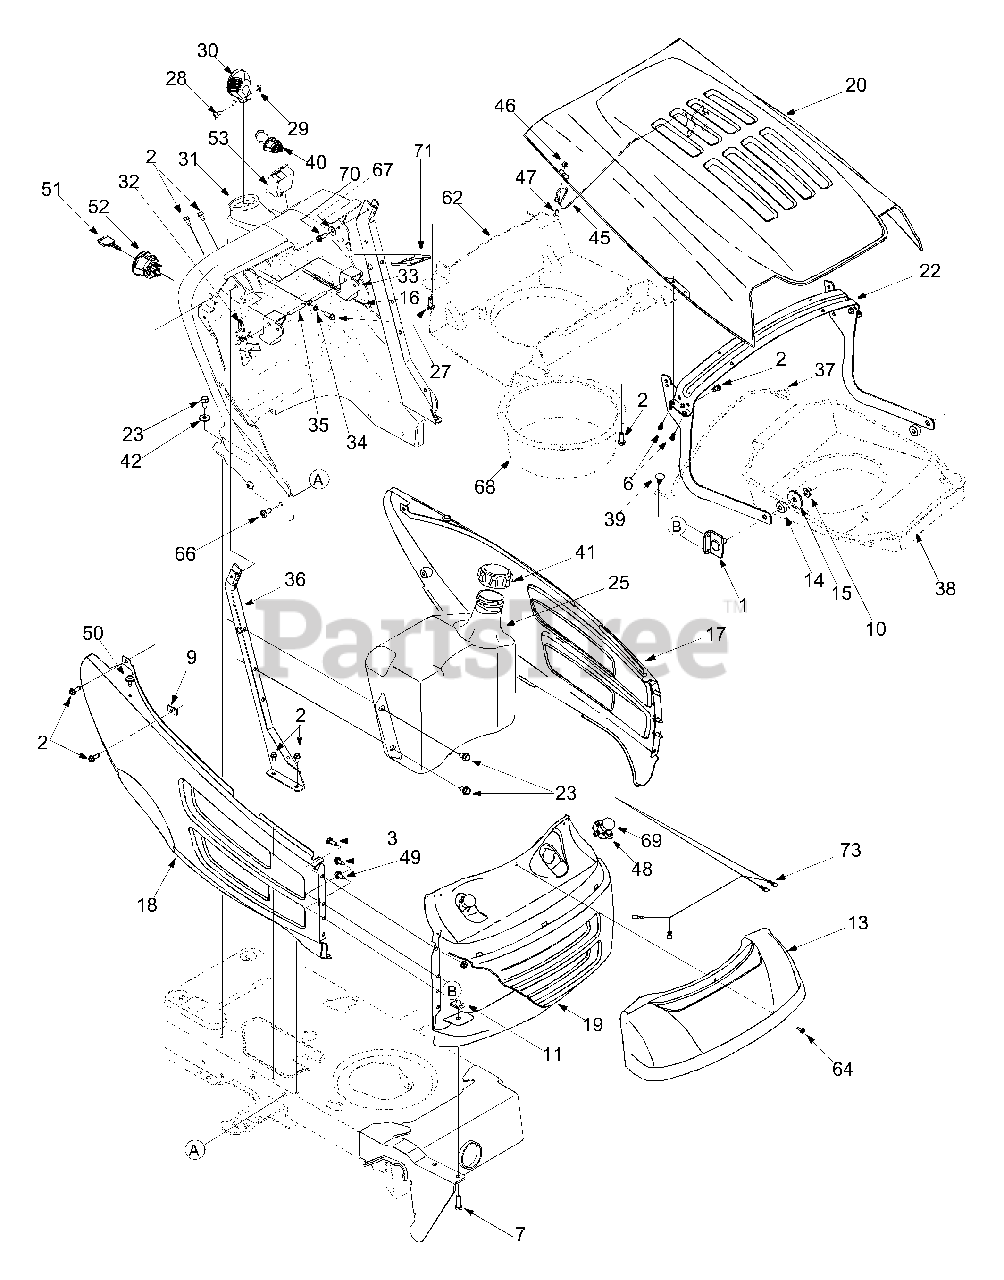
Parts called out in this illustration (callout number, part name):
2	Self-tapping Screw, 1/4-20 x .5
3	Hex Cap Screw, 1/4-20 x .62
4	Phillips Pan Screw, 1/4-20 x .75
6	Screw, #10-16 x .5
7	Hex Cap Screw, 5/16-18 x 1.0
8	Hex Sems Nut, 1/4-20
9	U-type Speed Nut, 1/4-20
10	Flange Lock Nut, 3/8-16
11	U-nut, 5/16-18
13	Headlight Lens
14	Rubber Washer, .87 x .33
15	Flat Washer, .406 x 1.5 x 11GA
16	Choke Knob/Cable (B&S Twin)
24	Fuel Tank, Three Gallon
25	Fuel Cap (fits either tank)
26	Self-tapping Screw, 1/4-20 x 1.25
27	Self-tapping Screw, 1/4-15 x .75
28	Truss Phillips Screw, #8-32 x .375
29	Hex Nut, #8-32
30	Throttle Control Knob
31	Dash Panel
32	Cruise Control Button
33	Parking Brake Button
34	Flat Washer, 9/32 x 1/2 x 1/16
35	Brake/Cruise Pivot Rod
38	Hood Plenum (B&S OHV V-Twin)
39	Ratchet Clip
40	Electric PTO Switch
41	Hex Flange Lock Nut, 1/4-20
42	Flat Washer, .349 x 1.0 x .063
45	Hood Latch
46	Hex Sems Nut, #10-32
47	Machine Screw, #10-24
48	Headlight Socket
49	Hex Index Washer Scr., 1/4-14 x .0625
50	Rubber Bumper
51	Ignition Key w/ plastic cover
52	Ignition Switch
53	Systems Ind. Monitor w/ Hour Meter
58	Clevis Pin, .50 x .78
59	Bumper Assembly
60	Internal Cotter Pin
61	Hood, Red
62	Hood Plenum
65	Choke Plug
66	Screw, 5/16-18 x .75
67	Bell Washer, .265 x .75 x .062
68	Intake Bellow (Intek Single & kohler)
69	Lamp
70	Self-tapping Screw, 1/4-20 x .75
71	Bracket: Elec. PTO Switch
72	Headlight Wire Harness
